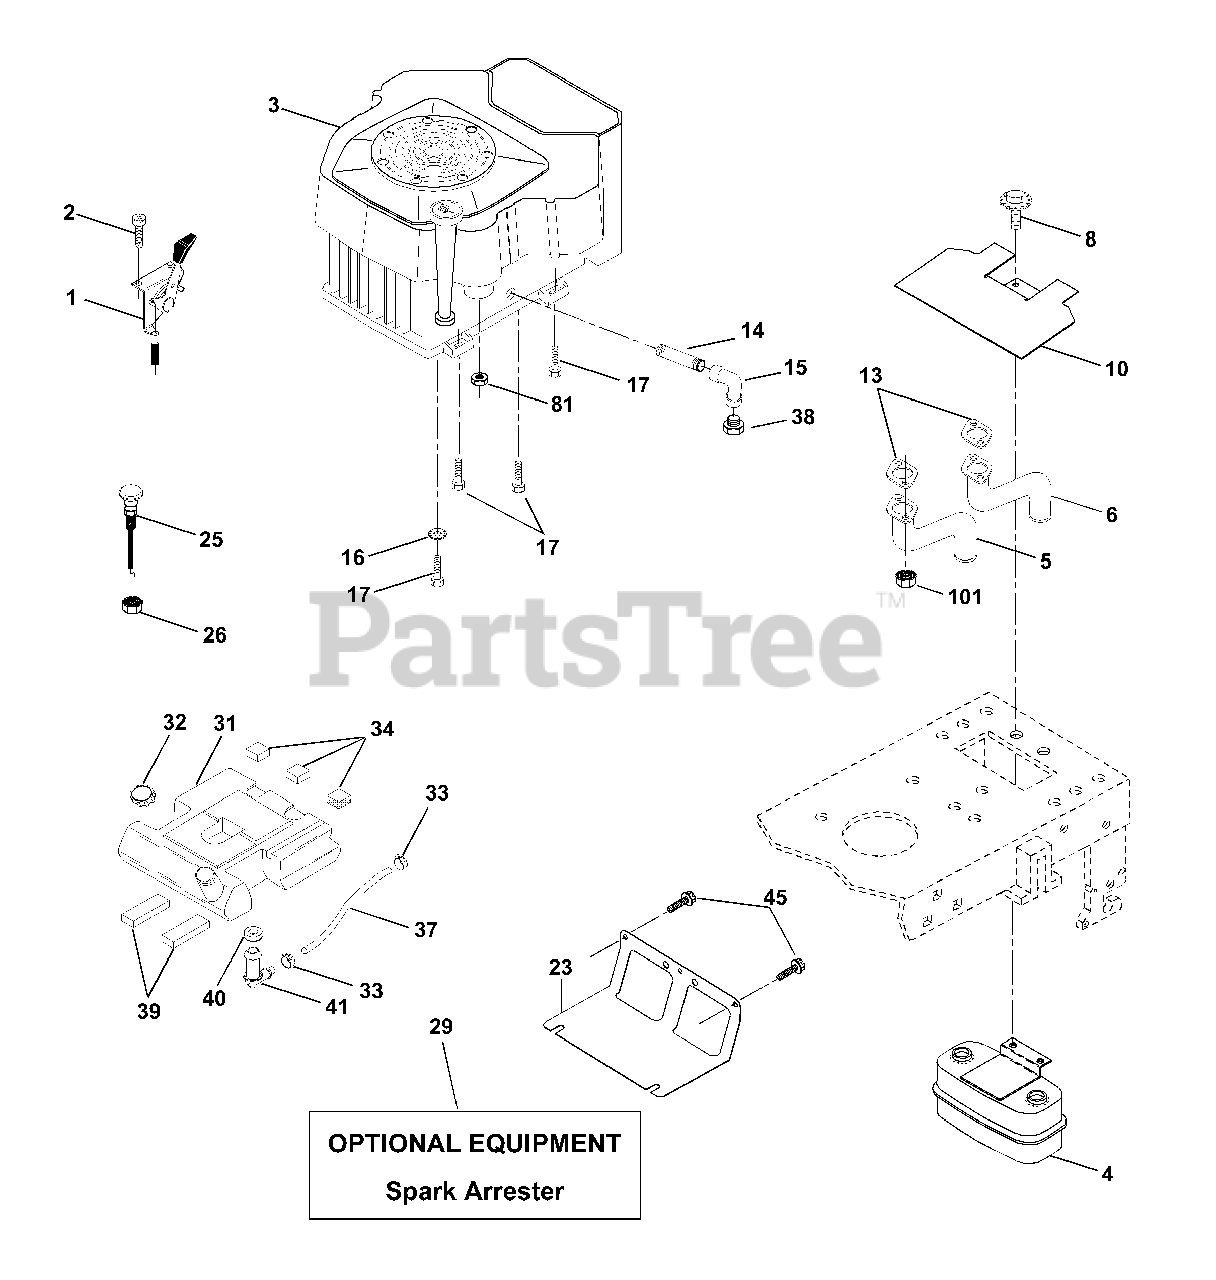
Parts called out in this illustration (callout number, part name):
1	Control, Throttle
2	Screw, Hex Head, Thread Cutting 1/4-20 x 5/8
5	Pipe Exhaust, LH
6	Pipe Exhaust, RH
8	Bolt 5/16-18 UNC x 3/4 w/Sems
10	Shield Heat Muffler
13	Muffler Gasket
14	Nipple, Pipe 3/8 NPT x 4-1/2
15	Elbow, Standard 90° 3/8-18 NPT
16	Washer, Lock, External Tooth 3/8
17	Screw Thdrol 3/8-16 x 1-1/2
23	Shield, Browning / Debris Guard
25	Choke Control
26	Nut, Keps 3/8-24 UNF
29	Kit, Spark Arrestor
31	Tank Fuel 3 50 Rear
32	Cap Asm Fuel W/sym Vented
33	Clamp, Hose
34	Pad, Spacer
37	Line, Fuel
38	Plug, Oil Drain
39	Pad, Idler
40	Bushing
41	Stem, Fuel Tank
45	Screw Hex Wsh Thdr 3/8-16 x 3/4
81	Nut, Keps Hex 1/4-20 Unc
101	Nut Flange M8-1.25 Non-Lk Zink
